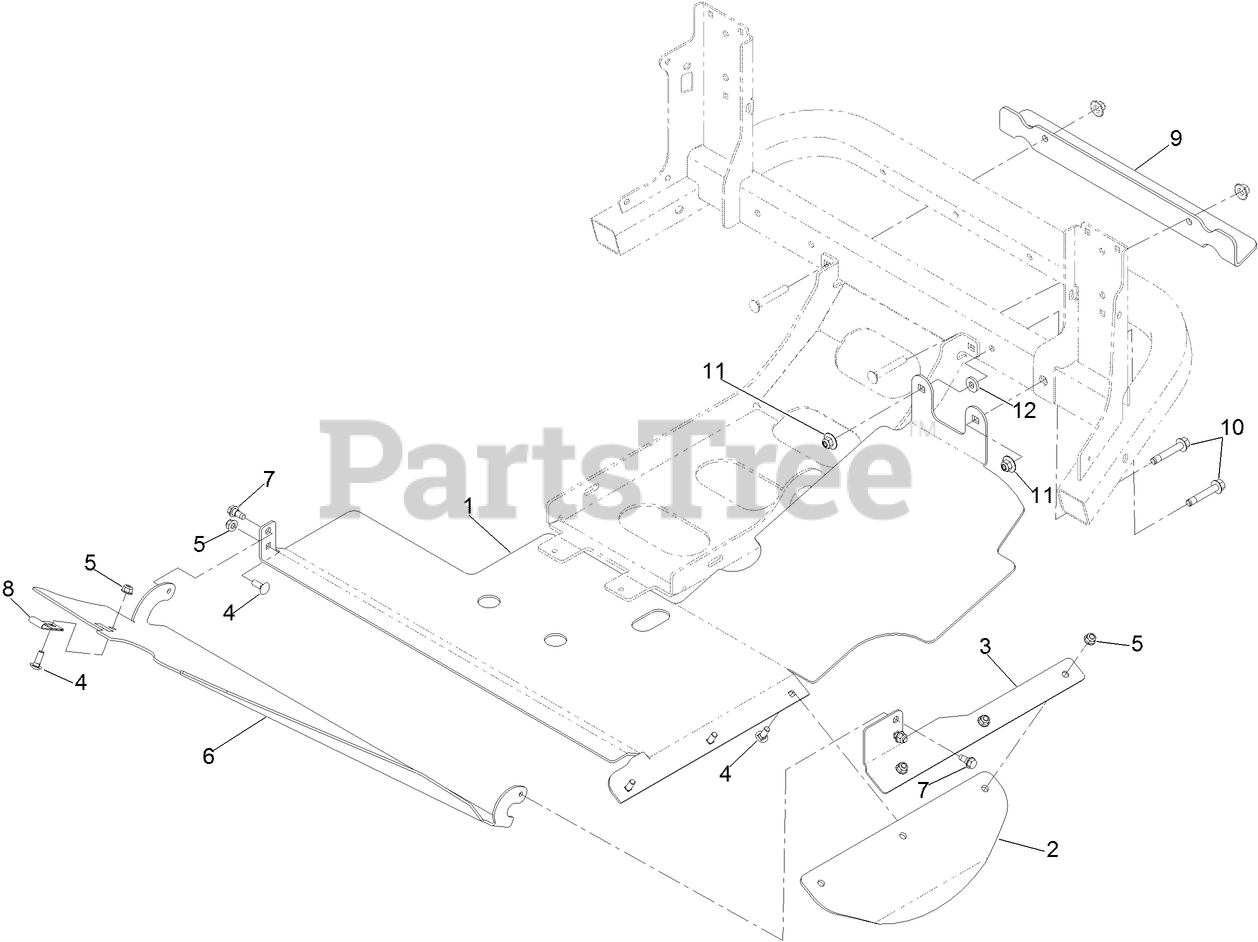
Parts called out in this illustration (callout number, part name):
1	PLATE-DISCHARGE
2	FLAP-RUBBER
3	BRACKET-FLAP, LH
4	SCREW-CARR
5	NUT-HF, NI
6	PANEL-DISCHARGE
7	SCREW-SHOULDER
8	BEARING-STRAP, NYLON
9	BRACKET-TIE DOWN
10	SCREW-HHF W/ PATCH
11	NUT-FLANGE, NI
12	SPACER
